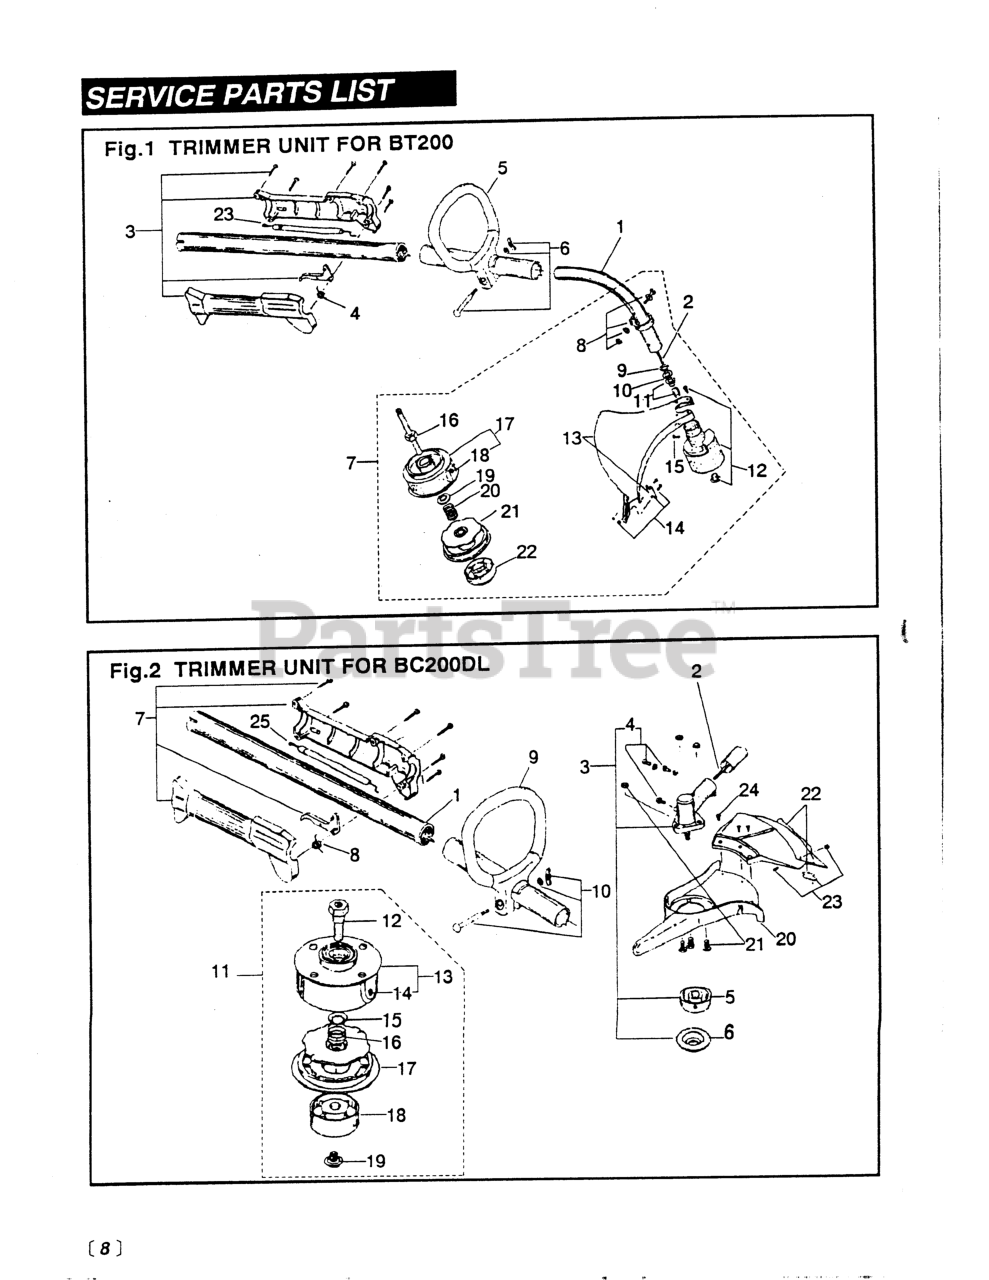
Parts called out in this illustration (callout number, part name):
1	DRIVE SHAFT HSG ASSY (BC)
3	GEARCASE ASSEMBLY
4	HARDWARE, MOUNTING
5	HOLDER (U), BLADE DRIVER
6	HOLDER (L) (RPLS 613222)
8	SPRING, THROTTLE TRIGGER
11	UBT200 - CUTTING HEAD ASSY.
12	SHAFT
13	HOUSING, OUTER SPOOL
14	EYELET
15	WASHER
16	SPRING, INNER REEL
17	REEL, INNER
18	KNOB (USE 180814)
19	KNOB, BUMP HEAD (USE 180814)
20	MOUNT, GUARD
21	GUARD MOUNT HDWE SET
22	GUARD ASSEMBLY
23	BLADE ASSEMBLY
24	SCREW, GUARD MOUNT ASSY
